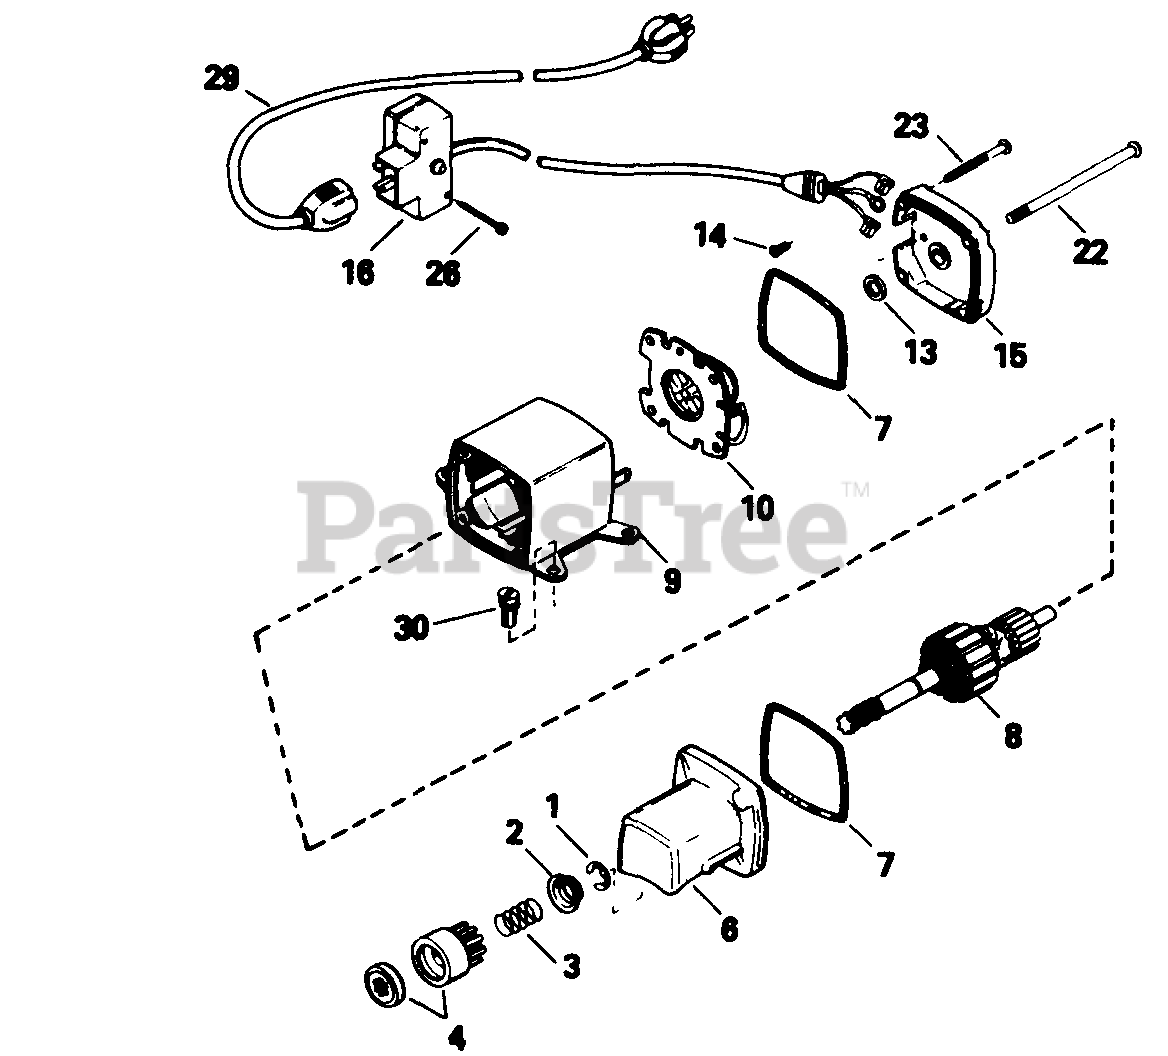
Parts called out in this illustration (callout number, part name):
1	Ring, Retainer
2	Retainer, Spring
3	Spring, Anti-Drift
4	Nut & Gear
6	Cap Ass'y., Drive End
8	Armature
9	Housing Ass'y.
10	Card Ass'y., Brush
13	Washer, Thrust
14	Screw, Ground
15	Cap Ass'y., Commutator End
16	Box Ass'y., Switch
22	Bolt, Case
23	Screw, Grounding
26	Screw, Hex Hd. Self-Tap, 6-32 x 2-1/2
29	Cord, Extension (10'6")
30	Screw, Hex Hd. Self-Tap, 1/4-20 x 11/16
